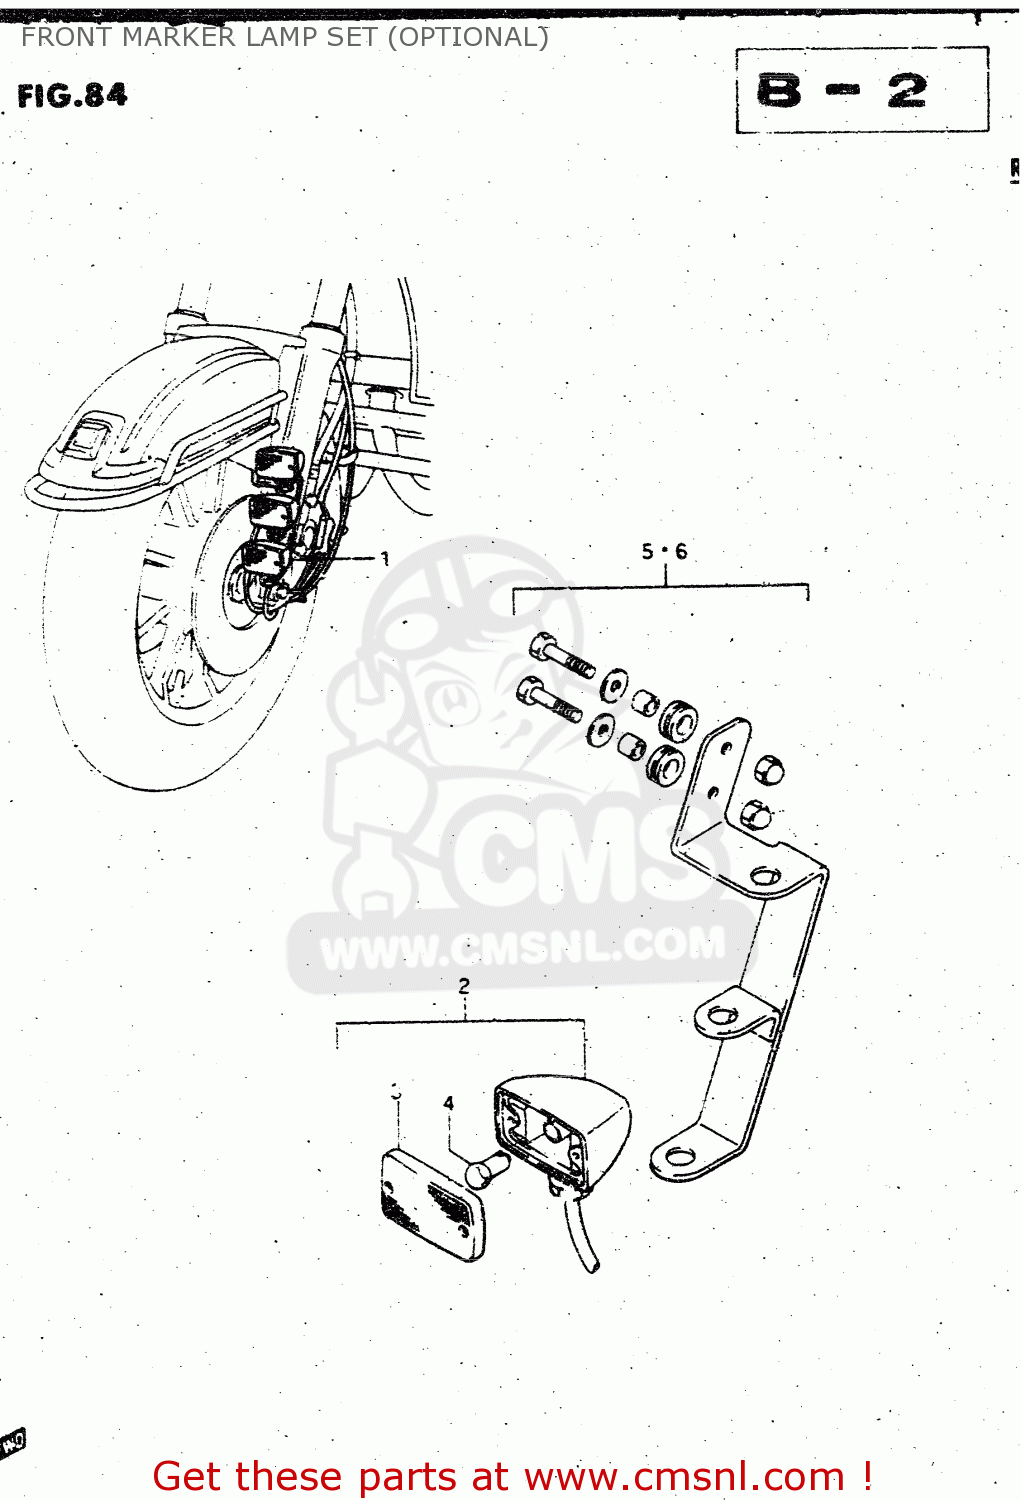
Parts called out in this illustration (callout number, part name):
1	REAR END,MARKER LAMP S
2	LAMP ASSY, FRONT MARKER
3	LENS
4	BULB 12V 3W
5	BRACKET SET, RH
6	BRACKET SET, LH
